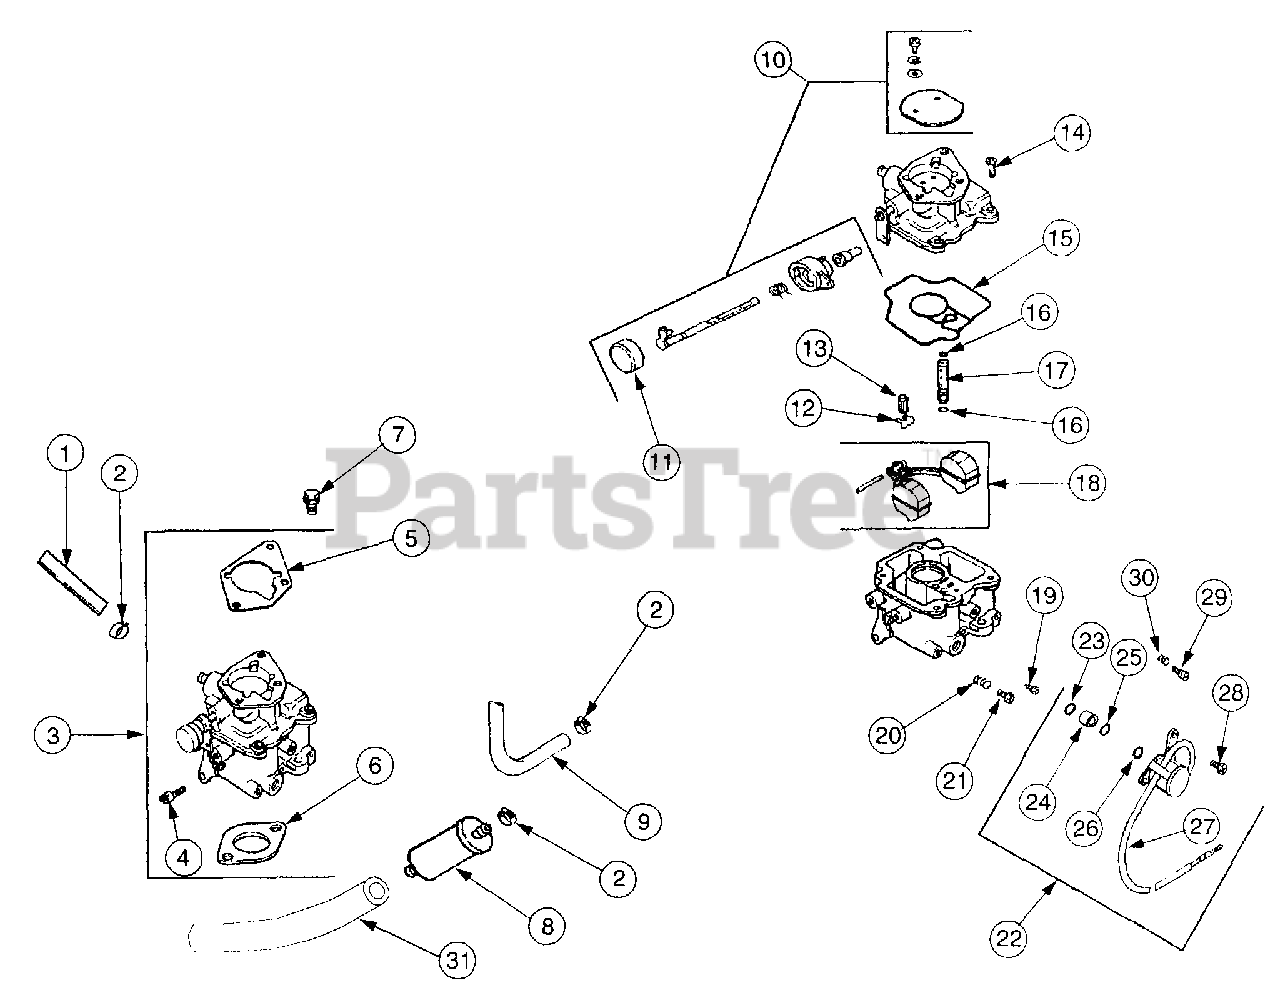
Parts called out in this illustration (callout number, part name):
1	Line, Fuel 10"
2	Clamp, Hose
3	Kit, Carburetor
4	Screw, Throttle Stop
5	Gasket, Air Cleaner Base
6	Gasket, Carburetor
7	Screw, Hex Flange
8	Filter, Fuel
9	Line, Fuel 11"
10	Kit, Choke Repair
11	Cap, Choke Lever
12	Clip, Inlet Needle Valve
13	Valve, Inlet Needle
14	Screw, Carburetor Body
15	Gasket, Carburetor
16	O-Ring, Slow Jet
18	Kit, Float Repair
20	Spring, Idle Adjust Screw
21	Screw, Idle Adjusting
22	Kit, Solenoid
24	Seat, Solenoid
27	Solenoid
28	Screw, Solenoid
29	Needle, Idle
30	Spring, Idle Needle
31	Insulation, Fuel Line
